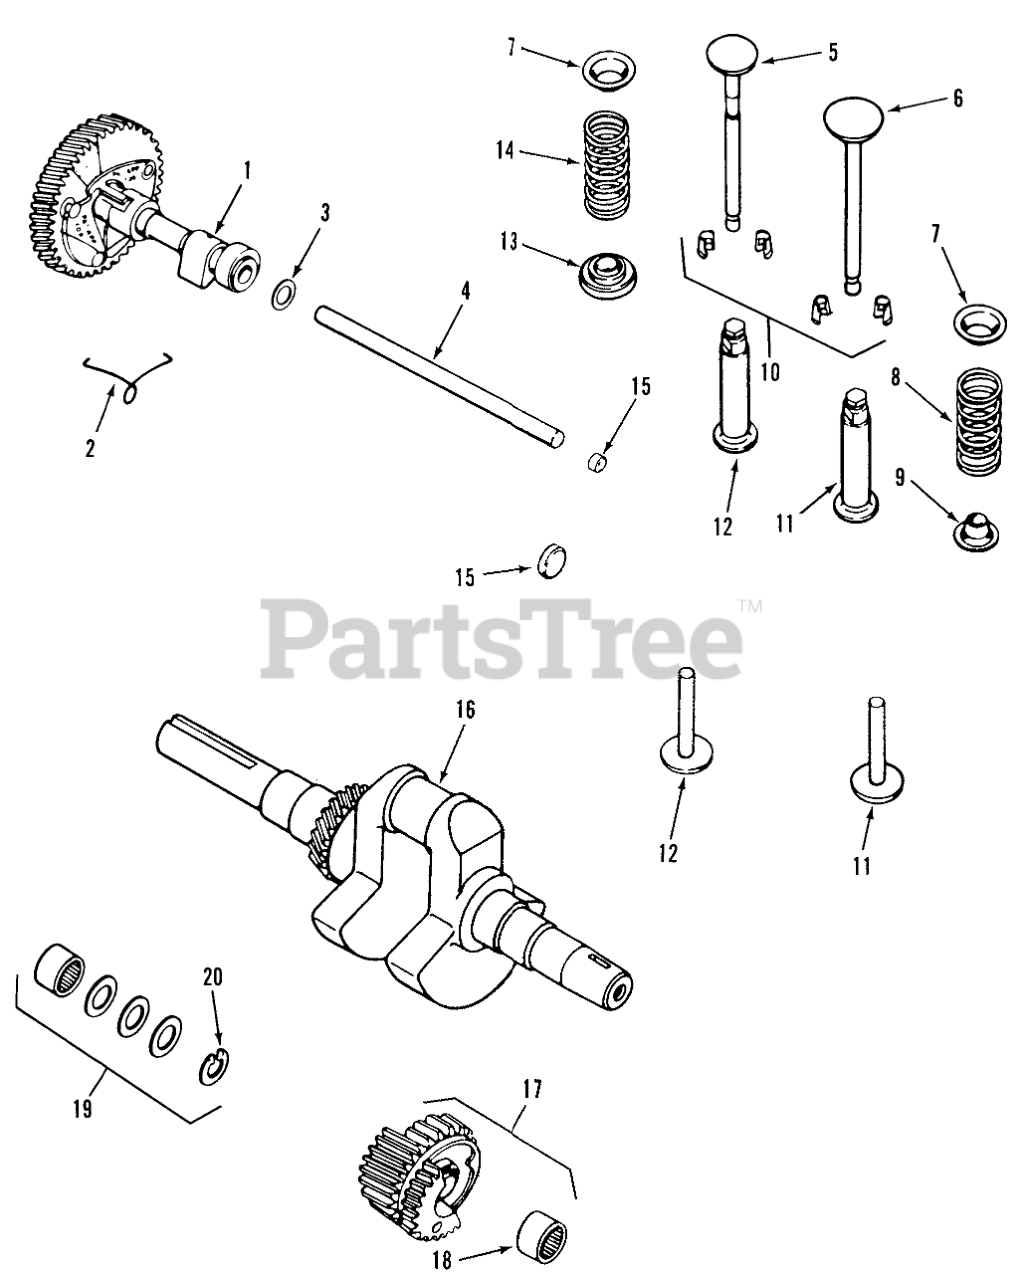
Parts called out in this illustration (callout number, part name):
1	Camshaft Assy (Includes Item 2)
2	Spring-Actuating
3	Spacer
4	Pin-Camshaft
5	Valve-Exhaust
6	Valve-Intake
7	Retainer-Spring
8	Spring
9	Retainer-Spring
10	Kit-Retainer
11	Tappet
12	Tappet
13	Rotator-Valve
14	Spring
15	Plug
16	Crankshaft Kit 3-25/32 x 1-1/8 (Includes Flywheel Hdwr.) 312
17	Gear Assembly (Includes Item 18) 312
18	Bearing-Needle
19	Spacer Kit (Includes Item 20) 312
20	Retainer
